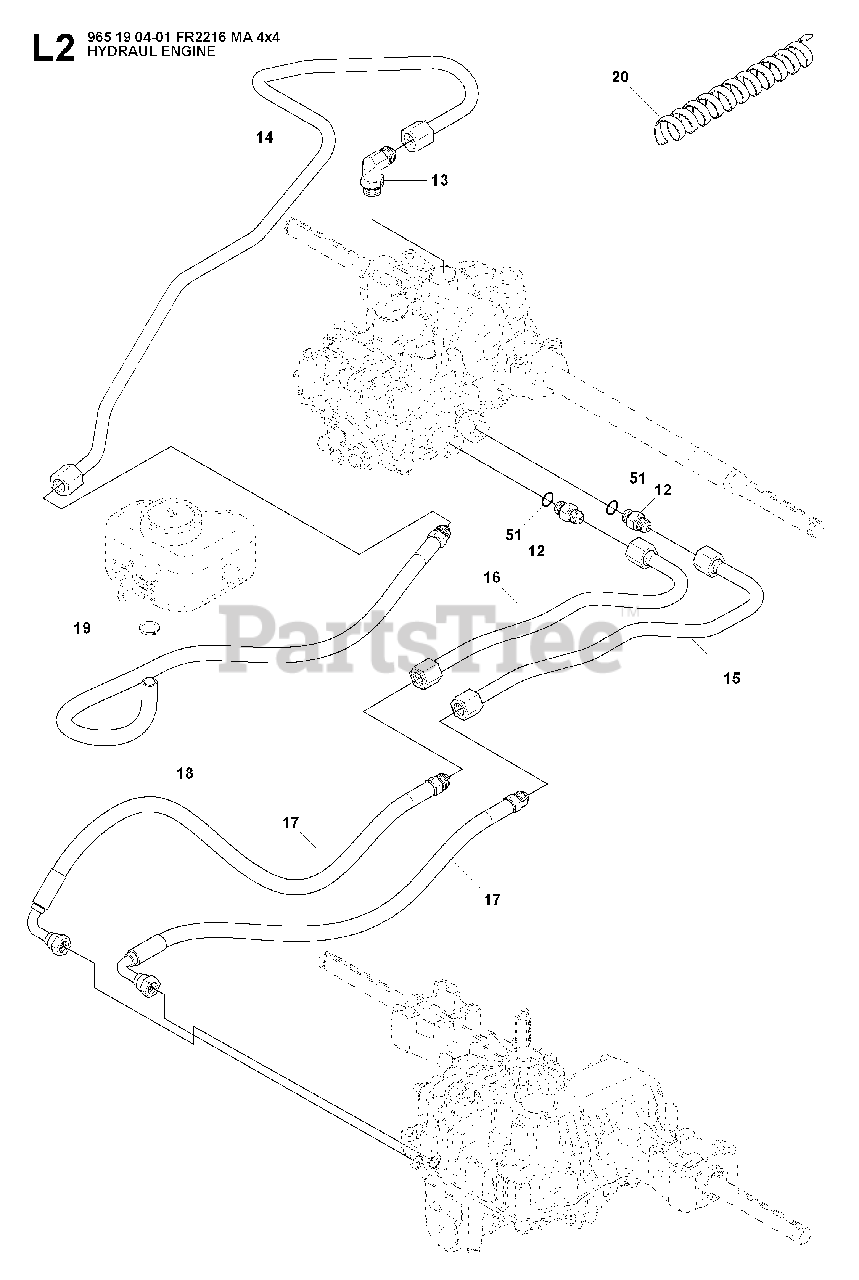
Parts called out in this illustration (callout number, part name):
12	PIPE FITTING
14	HYDRAULIC PIPE
15	HYDRAULIC PIPE
16	HYDRAULIC PIPE
17	HYDRAULIC HOSE
18	RP HOSE
19	CLAMP
20	PROTECTOR
